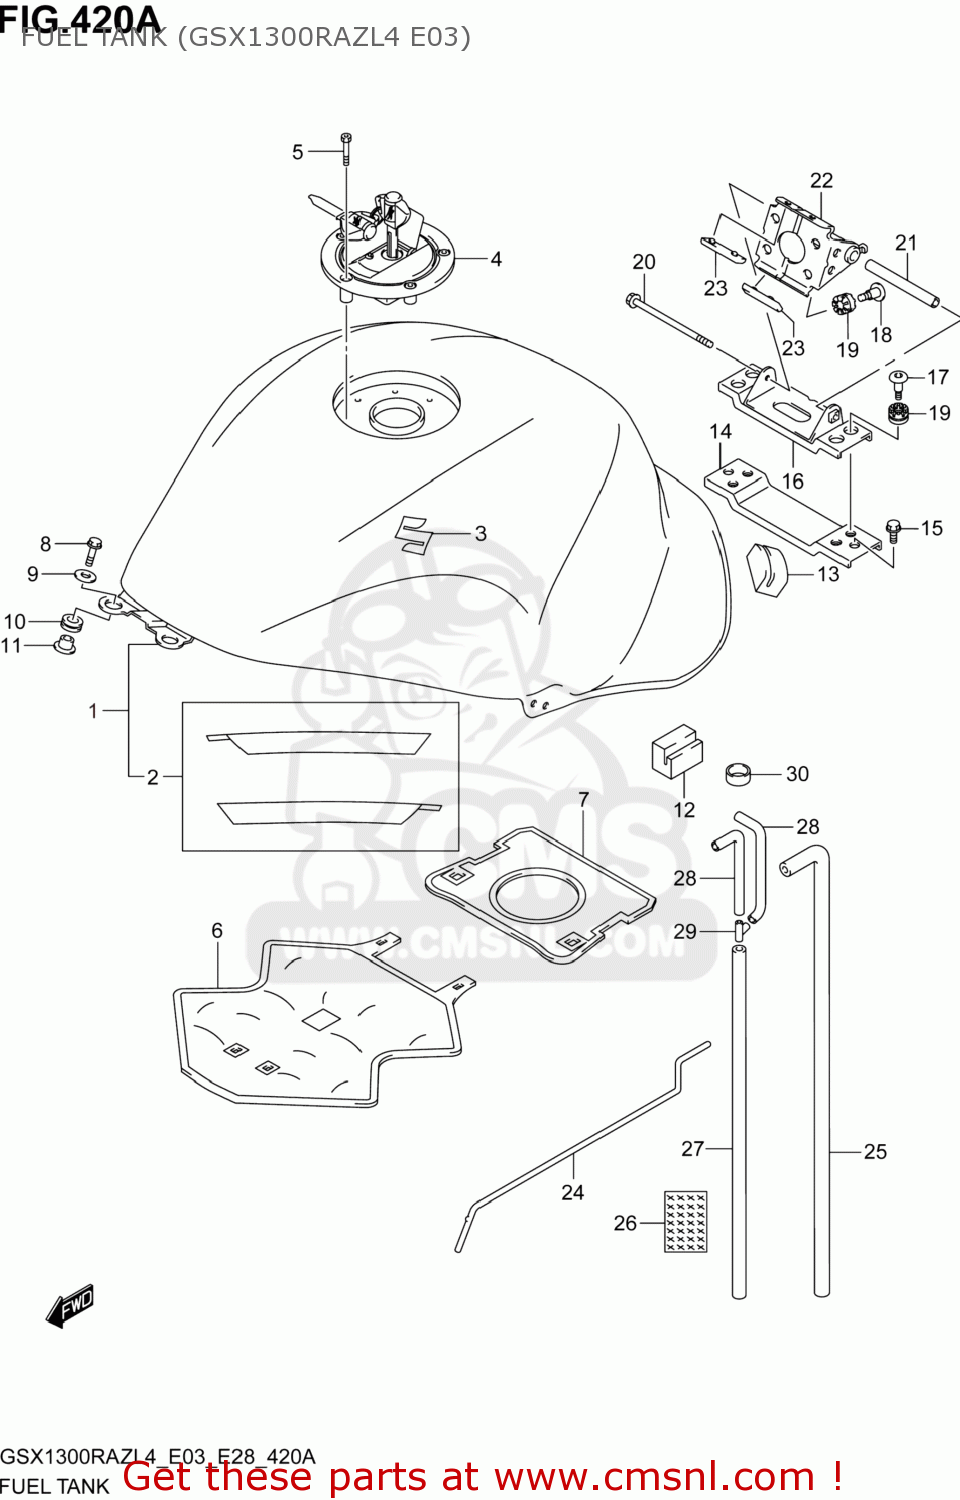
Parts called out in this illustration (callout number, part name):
1	TANK ASSY,FUEL
2	TAPE SET,FUEL TANK LOWER
3	EMBLEM, S
4	CAP SET,FUEL TANK
5	BOLT(5X20)
6	SHIELD,FUEL TANK HEAT NO.1
7	SHIELD,FUEL TANK HEAT NO.2
8	SCREW(6X25)
9	WASHER(6,5X22X1.6)
10	CUSHION,FUEL TANK FR
11	SPACER,FUEL TANK FR
12	CUSHION,FUEL TANK SIDE
13	CUSHION,FUEL TANK RR
14	BRACKET,FUEL TANK RR NO.3
15	BOLT
16	BRACKET,FUEL TANK RR NO.2
17	SCREW(6X22)
18	SCREW(6X22)
19	CUSHION
20	BOLT
21	SPACER,FUEL TANK RR
22	BRACKET,FUEL TANK RR NO.1
23	CUSHION,SEAT FR
24	STAY,FUEL TANK
25	HOSE,FUEL TANK DRAIN
26	SHIELD,DRAIN HOSE HEAT
27	HOSE,FUEL TANK BREATHER
28	HOSE,TANK BREATHER NO.2
29	3 WAY
30	HOSE(12X16X600)
